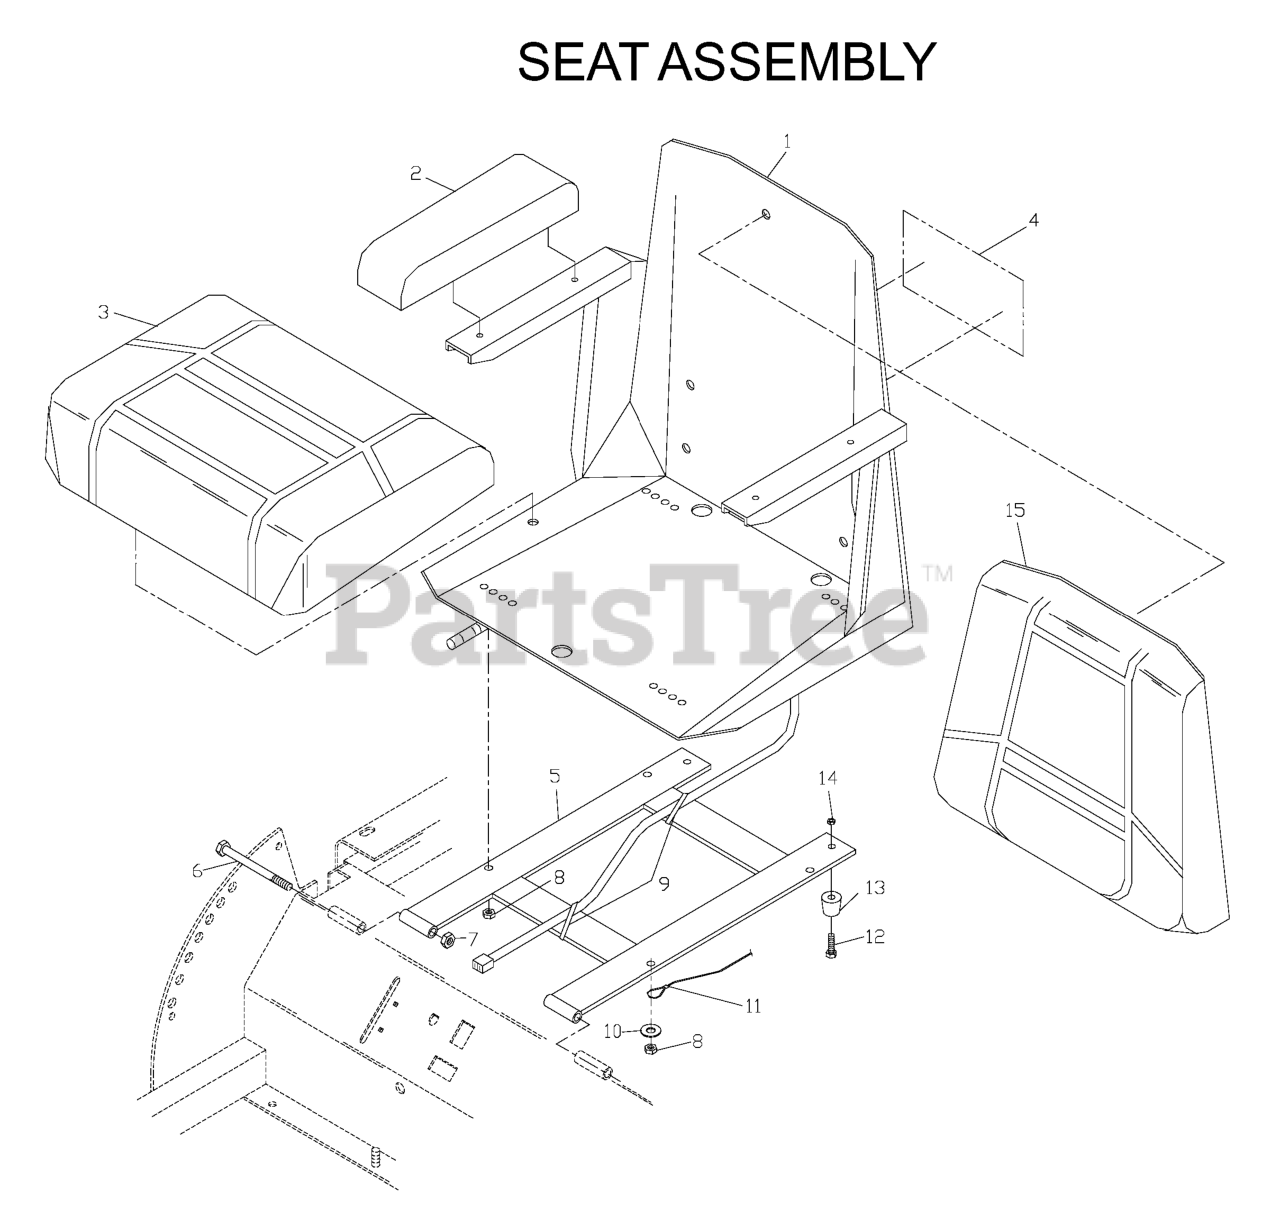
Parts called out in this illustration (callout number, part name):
1	SEAT, COMPLETE
2	ARM REST CUSHIONS/PAIR
3	SEAT CUSHION W/SWITCH
4	DECAL, CROWN H
5	SEAT MOUNT
6	HCS 3/8C X 4 1/2
7	NUT 3/8C CENTERBLOCK
8	NUT 5/16C CENTERLOCK
9	TIE, PLASTIC
10	WASHER 5/16 FLAT
11	SEAT LANYARD
12	SCREW, #1--24 X 1/2 SLOTTED
13	SEAT BUMPER
14	NUT 10-24 NYLOC
15	SEAT, BACK CUSHION
